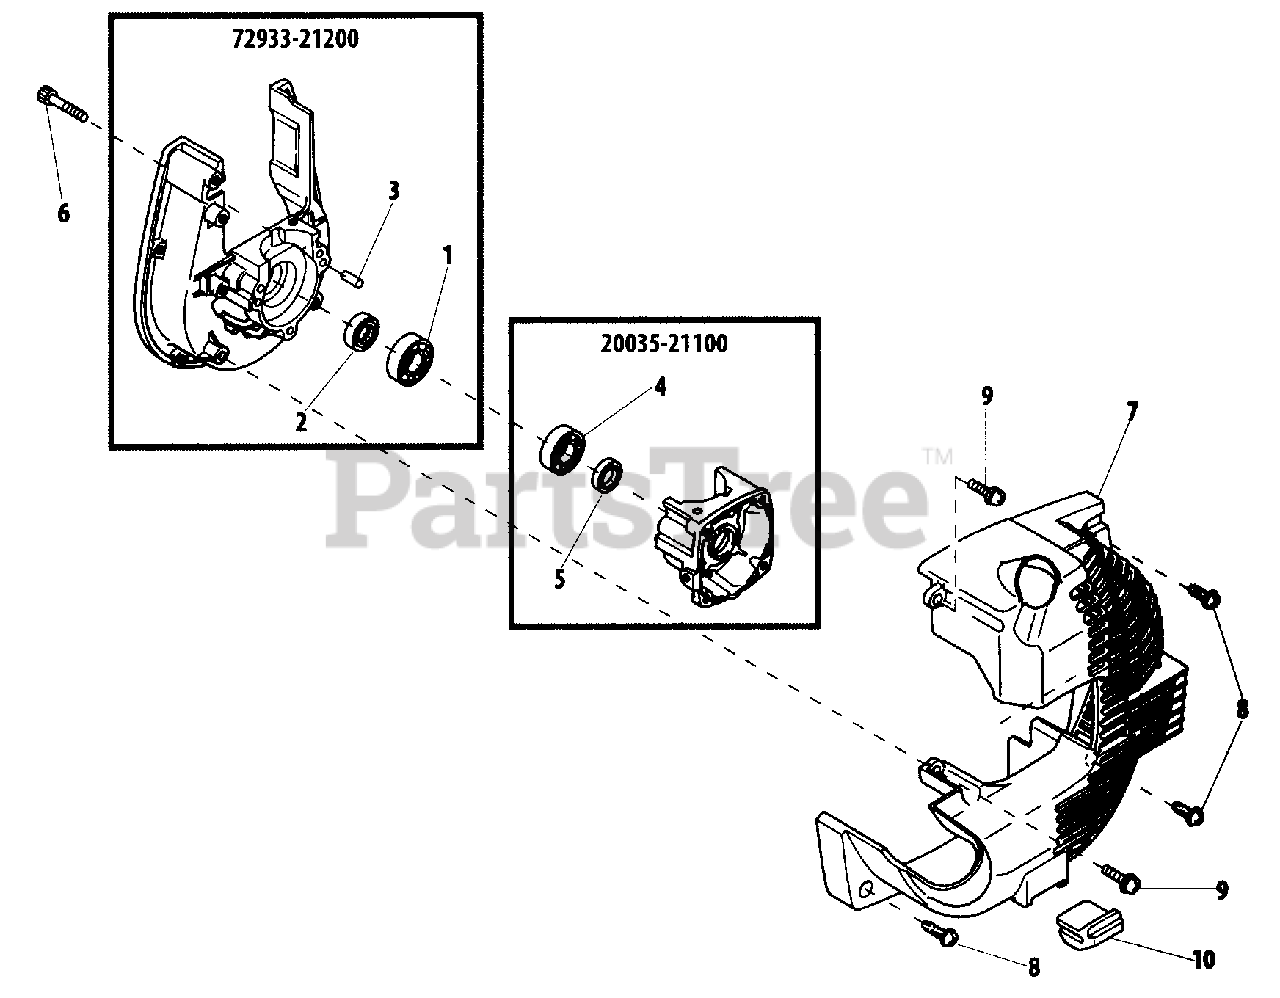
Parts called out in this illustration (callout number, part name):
1	BEARING, BALL - 6201
2	SEAL, OIL - 12
3	PIN - LOCATING
4	BEARING, BALL - 6001C3
5	SEAL, OIL
6	SCREW - 5X25
7	COVER, ENGINE
8	SCREW - 5X20
9	SCREW - 5X16
10	CUSHION
